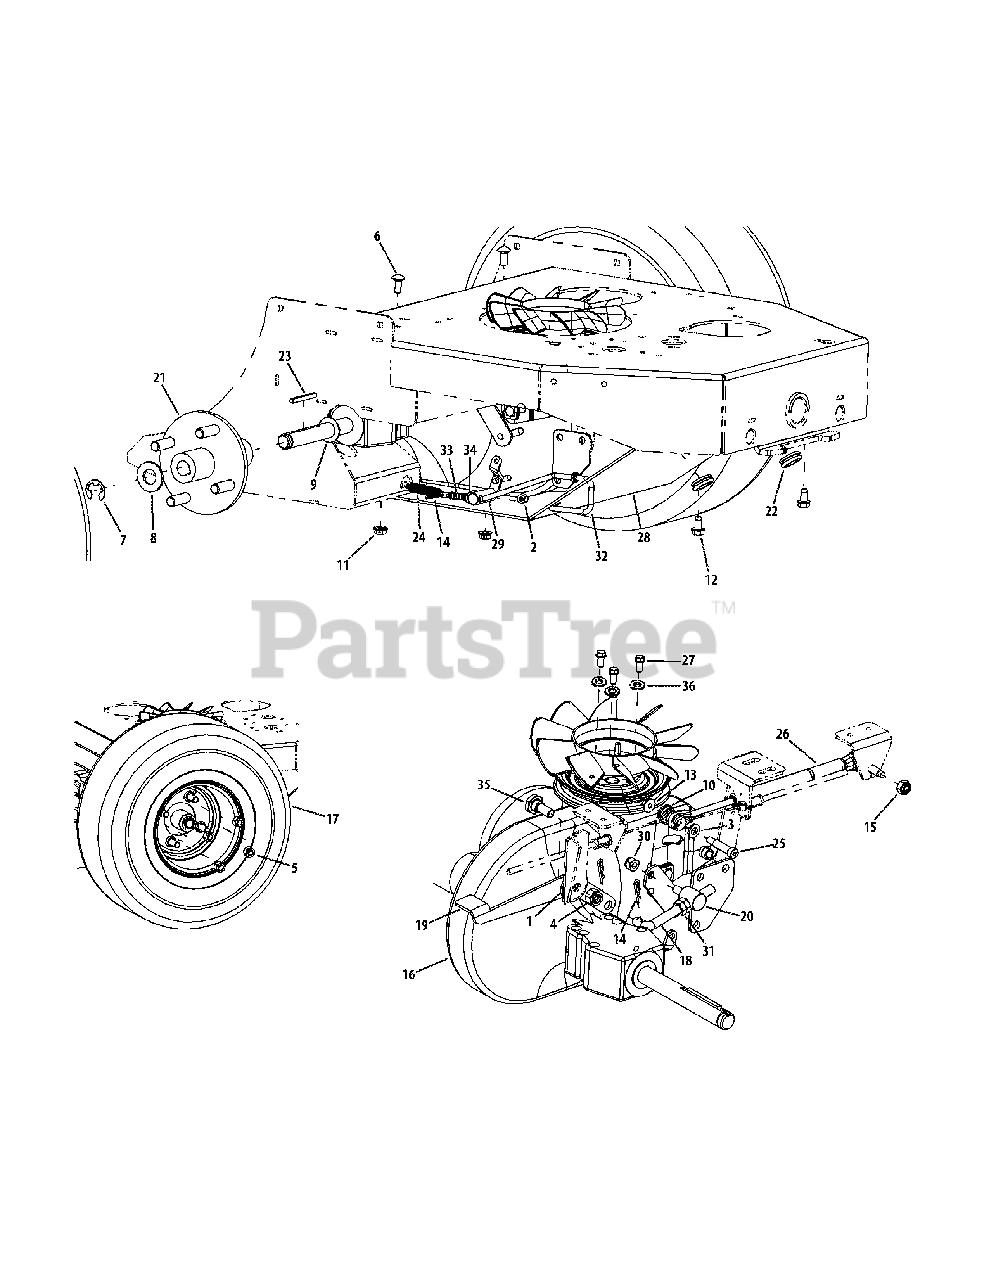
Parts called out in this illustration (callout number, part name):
1	Washer, 1/2
2	Lock Nut #10-24 w/Nylon Insert
3	Washer, 5/16
4	Nut, 3/8-16
5	Lug Nut, 1/2-20
6	Carriage Bolt, 5/16-18 x .75
8	Washer, .781 ID x 2.00 OD x .105
9	Washer, .06 x .776 x 1.25, SS
10	Washer, 1/4 x .630 x .0515
11	Nut, 5/16-18, Hex Flange Lock
12	Self Tapping Screw, 5/16-18 x .625
13	Nut, 1/4-20
14	Cotter Pin, .072 x 1.12 Long
15	Nut, M8, Top Lock
16	Transmission, Hydro Gear
17	Wheel Assembly, 18 x 6.50-8
18	Brake Lever Rod
19	Brake Lever
20	Pivot Brake Joint
20	Ferule, .750 x .313
21	Wheel Hub Assembly
22	Rubber Grommet
23	Key, 3/16 x 3/16 x 2
24	Extension Spring
25	Shoulder Bolt, 5/16 x 1.00
26	Damper Assembly
27	Self Tapping Screw, 1/4-20 x .75
28	Transmission Skid Plate
29	Ferule, .625 x .25
30	Nut, 5/16-18, Nylock
31	Hex Jam Nut, 3/8-24
32	Bypass Rod
33	Spring, 0.340 x 1.38LG
34	Washer, .265 x .562 x .025
35	Shoulder Bolt, .500 x .270, 3/8-16
36	Washer, Lock
